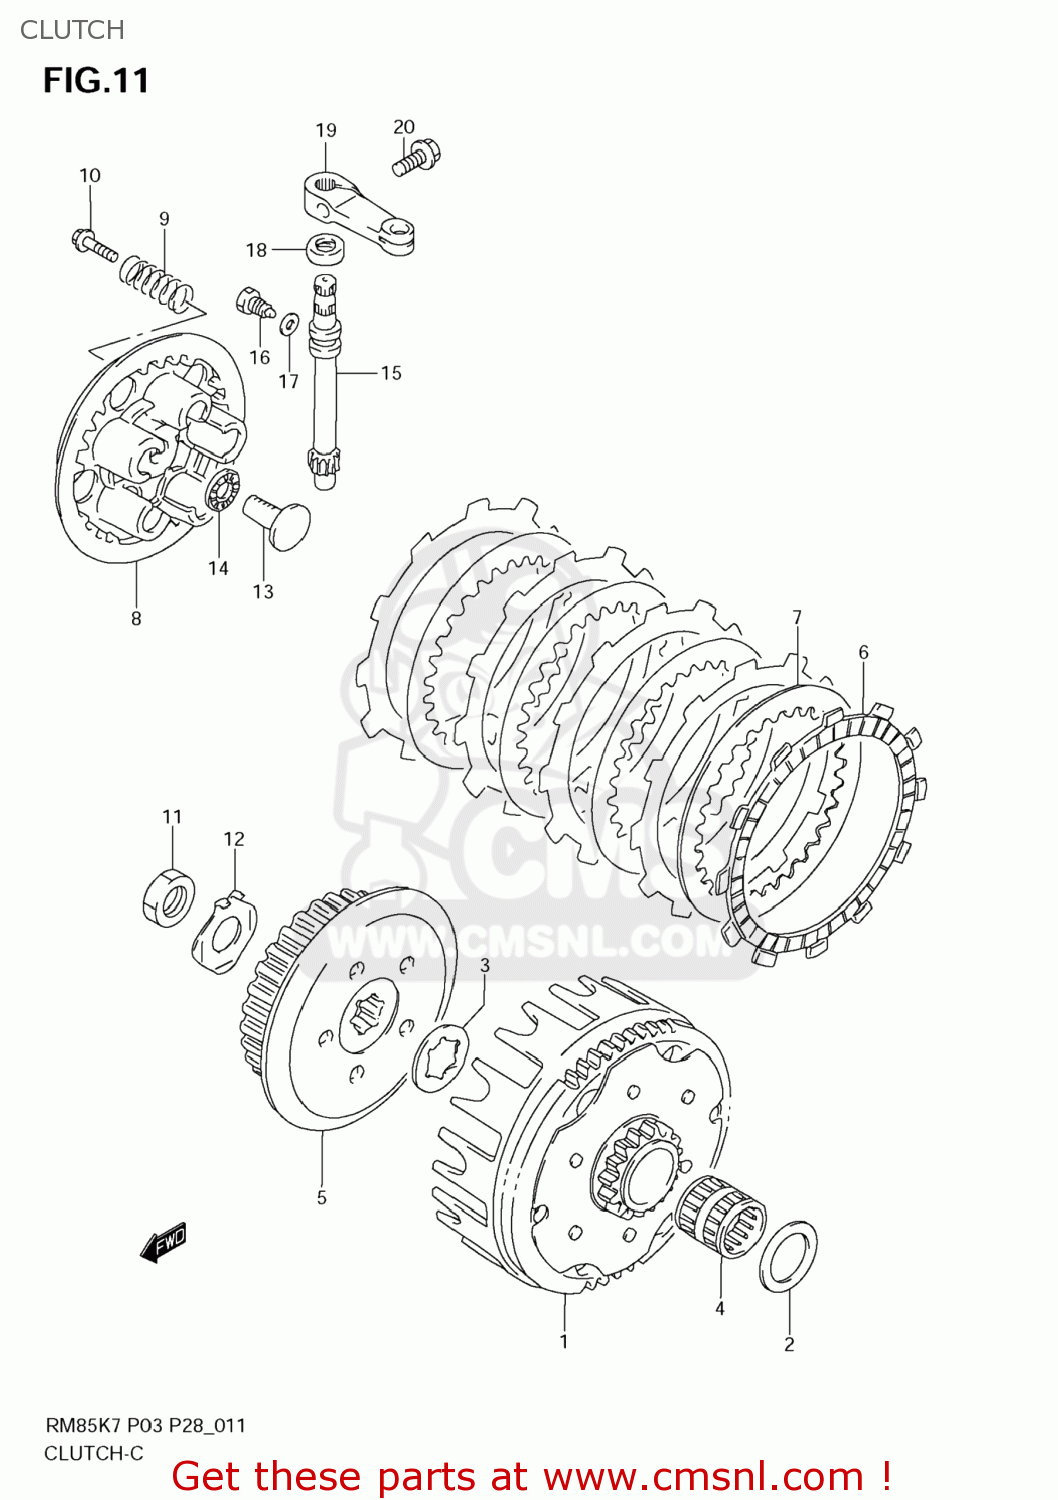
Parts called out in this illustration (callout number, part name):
1	GEAR ASSY,PRI DRIVEN(NT:62/16)
2	SHIM(20X32X1)
3	WASHER,LOCK
4	BEARING(20X25X26)
5	HUB,CLUTCH SLEEVE
6	PLATE,CLUTCH DRIVE(T:3.0) (NAS)
7	PLATE,CLUTCH DRIVEN(T:2.0) (NAS)
8	DISC,CLUTCH PRESSURE
9	SPRING
10	BOLT(5X20)
11	NUT
12	WASHER
13	RACK,CLUTCH RELEASE
14	BEARING(10X22X2.8)
15	PINION,CLUTCH RELEASE
16	BOLT(6X10)
17	GASKET(6.2X11X1).2 (NAS)
18	SEAL,OIL(10X17X5)
19	ARM,CLUTCH RELEASE
20	BOLT(6X16)
